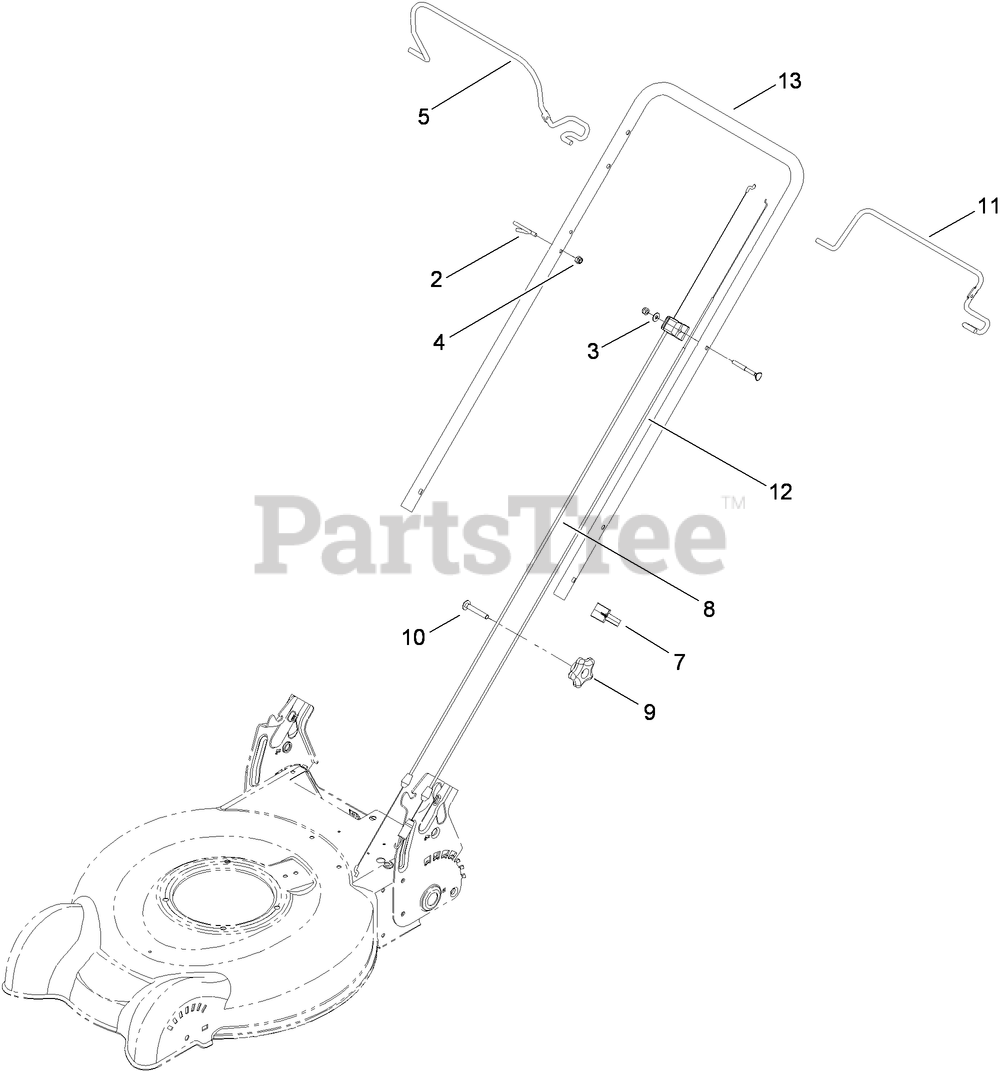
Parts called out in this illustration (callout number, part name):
2	GUIDE-ROPE
3	WASHER-FLAT
4	NUT-LOCK, NI
7	GUIDE-CABLE
8	CABLE-BRAKE
9	KNOB-HANDLE
10	BOLT-CARR
11	BAIL-TRACTION, 2-BAIL FLAT
12	CABLE-TRACTION
13	HANDLE-UPPER
